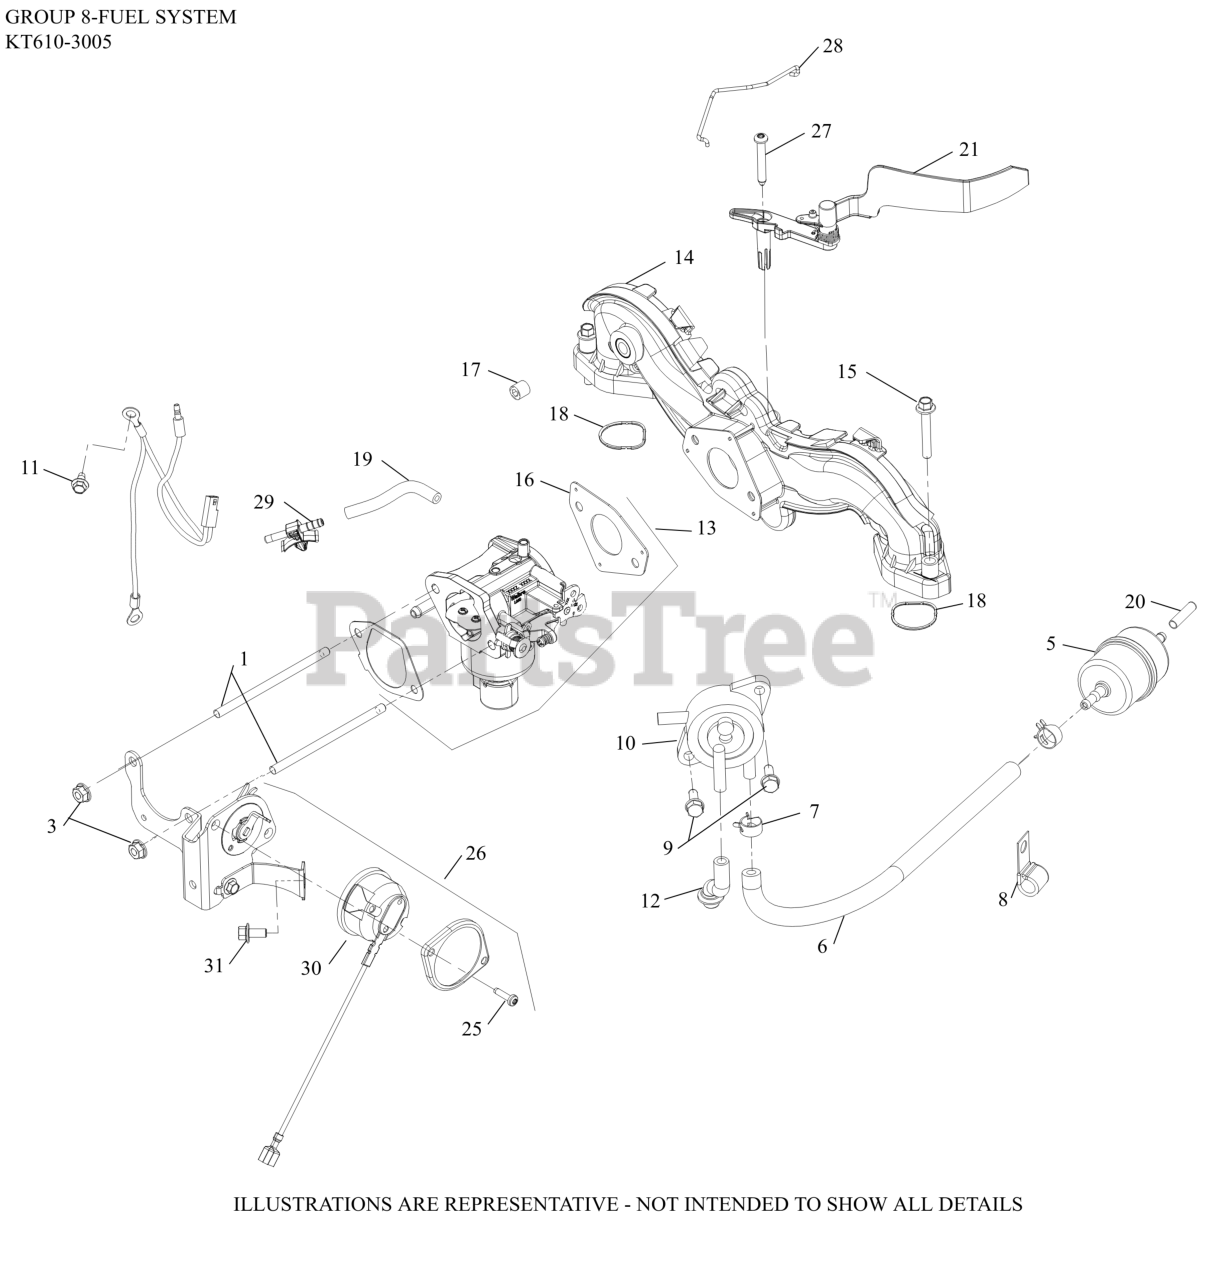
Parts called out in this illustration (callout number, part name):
3	NUT, FLG M6X1.0
5	FILTER, FUEL
6	HOSE,LW PERM.FUEL 24.00"-USE 25 111 81-S
7	SPRING CLAMP, HOSE
8	CLIP, CABLE
9	SCREW, TAP M6X1.7X18
10	PUMP, FUEL (PULSE)-(#2539326S)
11	SCREW, THREAD FORMING
12	HOSE, PULSE PUMP(STEEL COVERS)
13	KIT,CARB(WALBRO)
14	KIT, INTAKE MANIFOLD-(#24164277S)
15	SCREW, FLG M6X1.0X40
16	GASKET, CARBURETOR
17	PLUG, CTSK PIPE 1/8"
18	O-RING, INTAKE PORT (PIM)
19	HOSE EVAPORATIVE (WALBRO)
20	CAP, MASKING
21	DEFLECTOR ASSEMBLY, AIR VANE
25	SCREW, PAN HEAD THREAD FORMING (M4)
26	THERMOSTAT ASSY (CDI) - USE 32 755 27-S
26	THERMOSTAT ASSY(MDI IGN)-USE 32 755 27-S
27	SCREW, PAN HEAD (#12-14 X 38 MM)
28	LINKAGE, CHOKE UPLOADER
29	CONNECTOR, EVAPORATIVE
30	KIT, THERMOSTAT, ELECTRIC CHOKE
31	SCREW, FLG M6X1.0X12
NI	KIT,REPAIR OVERHAUL(WALBRO)
NI	KIT,BOWL O-RING(WALBRO)
NI	KIT, HI ALTITUDE (5000 FT) 19MM
NI	KIT,SOLENOID REPAIR(WALBRO)
NI	KIT,REPAIR FLOAT(WALBRO)
